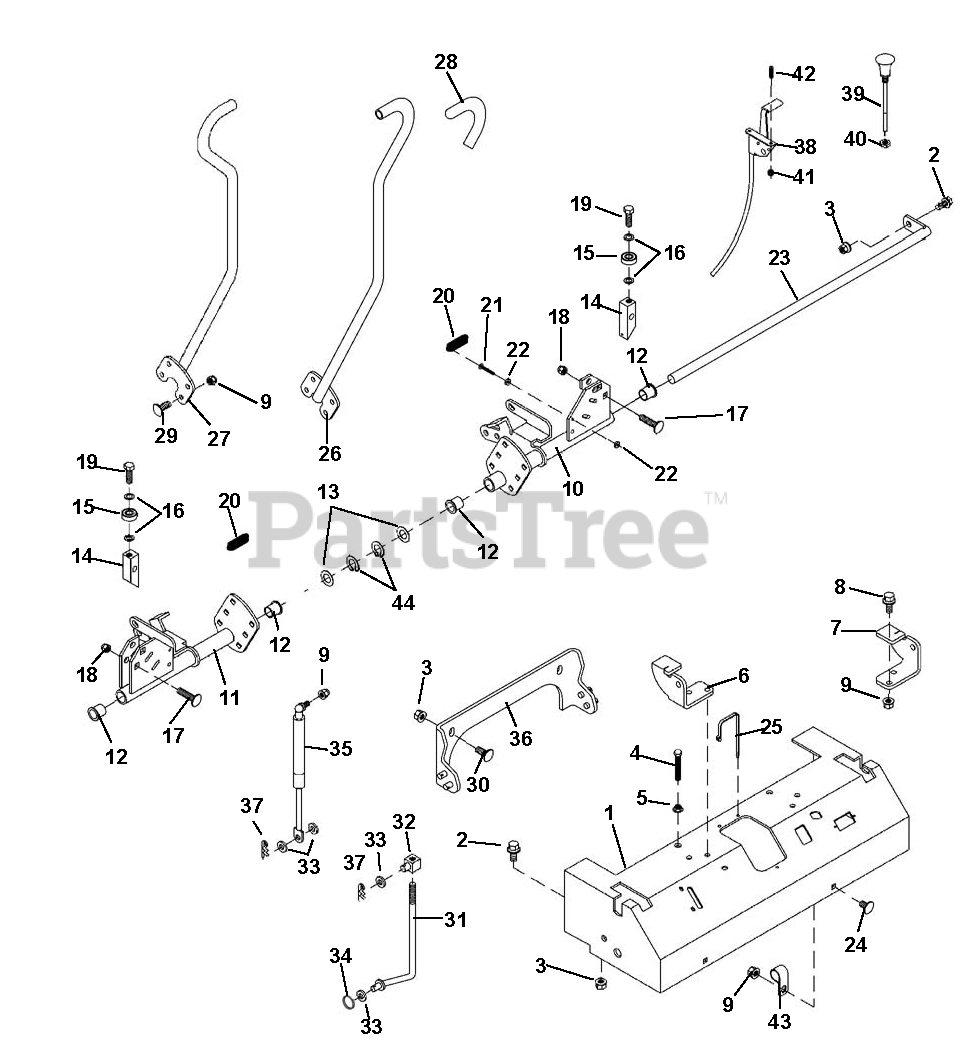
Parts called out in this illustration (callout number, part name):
1	CONSOLE PLATE W/DECALS S/O
2	SCREW,HEX,FL,JDS123,M10X1.5X25
3	LOCKNUT, M10X1.50 WHIZ GR10 Y
4	CAP SCREW, HEX HEAD
5	SPINLOCK NUT - 1/4
6	BRACKET, RH SEAT PLATE
7	BRACKET, LH SEAT PLATE
8	SCREW,HEX,FL,JDS123,M8X1.25X25
9	LOCKNUT, M8X1.25 NYLOC FLG 10Y
10	PIVOT, CONTROL L.H.
11	PIVOT, CONTROL R.H.
12	BUSHING, NYLON
13	WASHER, .627X1.09X.030 THST Y
14	ARM, CONTROL
15	BRG, BAL M10XM26XM8 - 60002RS
16	SHIM, CIRCULAR
17	BOLT,RH,SQNECK,JDS137,M10X1.5X
18	LOCKNUT, M10X1.50 NYLOC Y
19	BOLT, 3/8 X .75 A17D ZINC HEX
20	SPRING, PARK BRAKE
21	SCREW, PAN HEAD 10-24X1.25 SS
22	NUT, 3/16 HEX MACHINE 1020 ZIN
23	PIVOT,CONTROL SHAFT-PLATED
24	BOLT, M8X1.25X20 CRG 8.8 Y
25	CABLE TIE, .15 X 8.50
26	WLDT, CONTROL LEVER LH
27	WLDT, CONTROL LEVER RH
28	GRIP, CONTROL
29	BOLT, M8X1.25X20 CRG 8.8 Y
30	SCREW, HEX FLANGE HEAD
31	ROD, CONTROL
32	SWIVEL, 3/8-24
33	SHIM, CIRCULAR
34	RING, LOCKING
35	ABSORBER, ASM. WITH BALL STUD
36	WLDT, DAMPNER BRACKET
37	PIN, HAR .094X1.53 5/16-1/2 Y
38	ACCELERATOR
39	CABLE, CHOKE57.0"
40	NUT, .375 UNF2B HEX JDS14 8 ZN
41	#8.32 ELASTIC STOP NUT
42	SCREW,.164X.500 ZN RD HD MACH
43	P-CLIP, .750 INSULATED
44	RING, RETAINING
